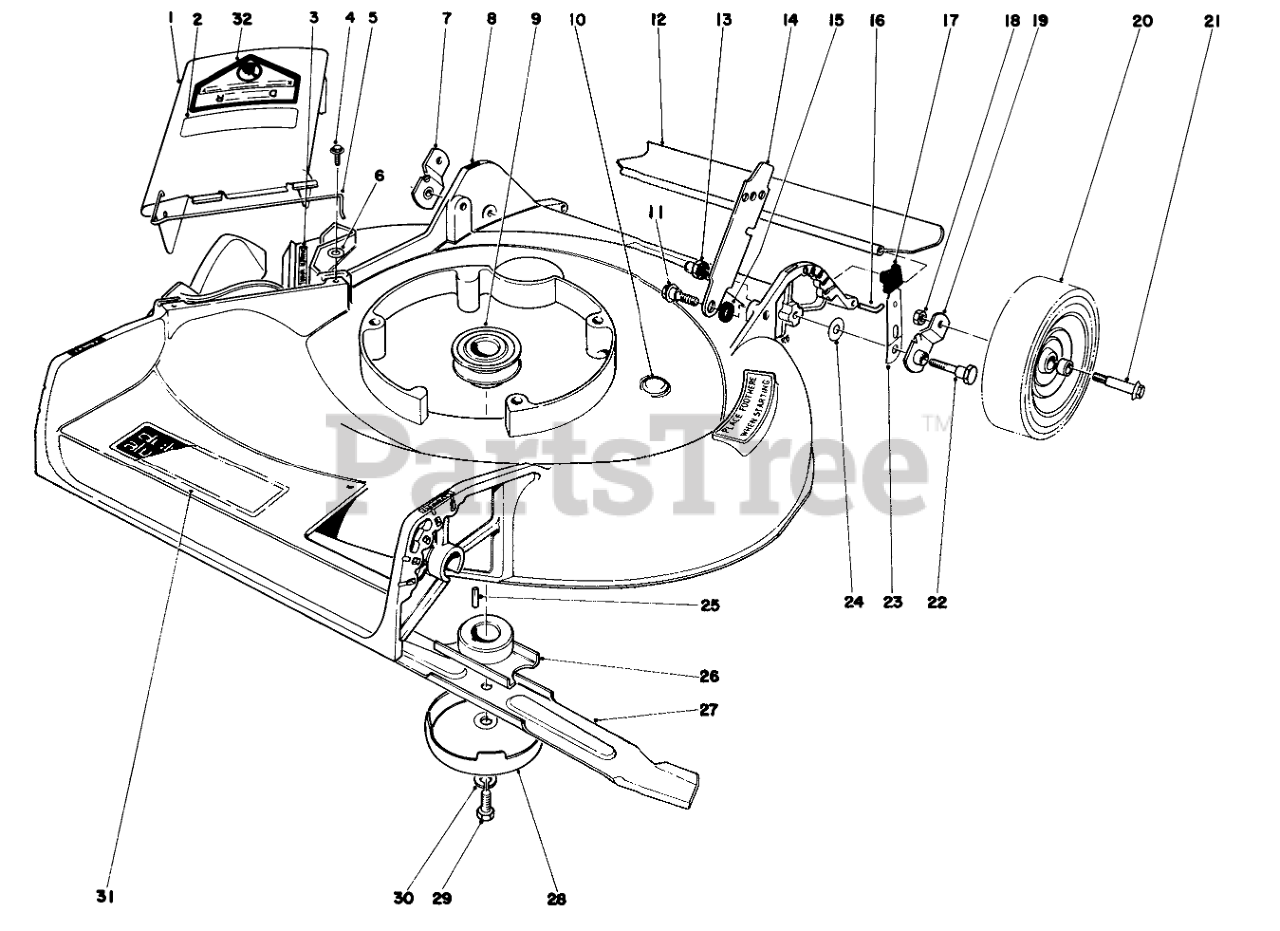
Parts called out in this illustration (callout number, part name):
1	Deflector Cover Assembly (Incl. Ref. #2, 5 & 32)
2	DECAL DEFLECTOR
3	Decal
4	SCREW
5	SPRING HINGE
6	WASHER-FLAT
7	Pivot Arm
8	Housing
9	DRIVER PULLEY
11	SCREW-SHOULDER
12	Rear Shield
13	HANDLE PIVOT NUT
14	Latch
15	SPACER
16	SHIELD ROD
17	KNOB-ARM
18	Nut
19	Pivot Arm
20	WHEEL TIRE ASM 8 IN
21	BOLT-WHEEL
22	5/16-18 PIVOT SCREW
23	SPRING ARM ASM
24	Washer
25	KEY-SQUARE
26	Blade Retailer
27	Blade
28	Anti Scalp Cup
29	SPECIAL SCREW
30	WASHER-LOCK
31	Decal-Deck
32	DECAL-DANGER
